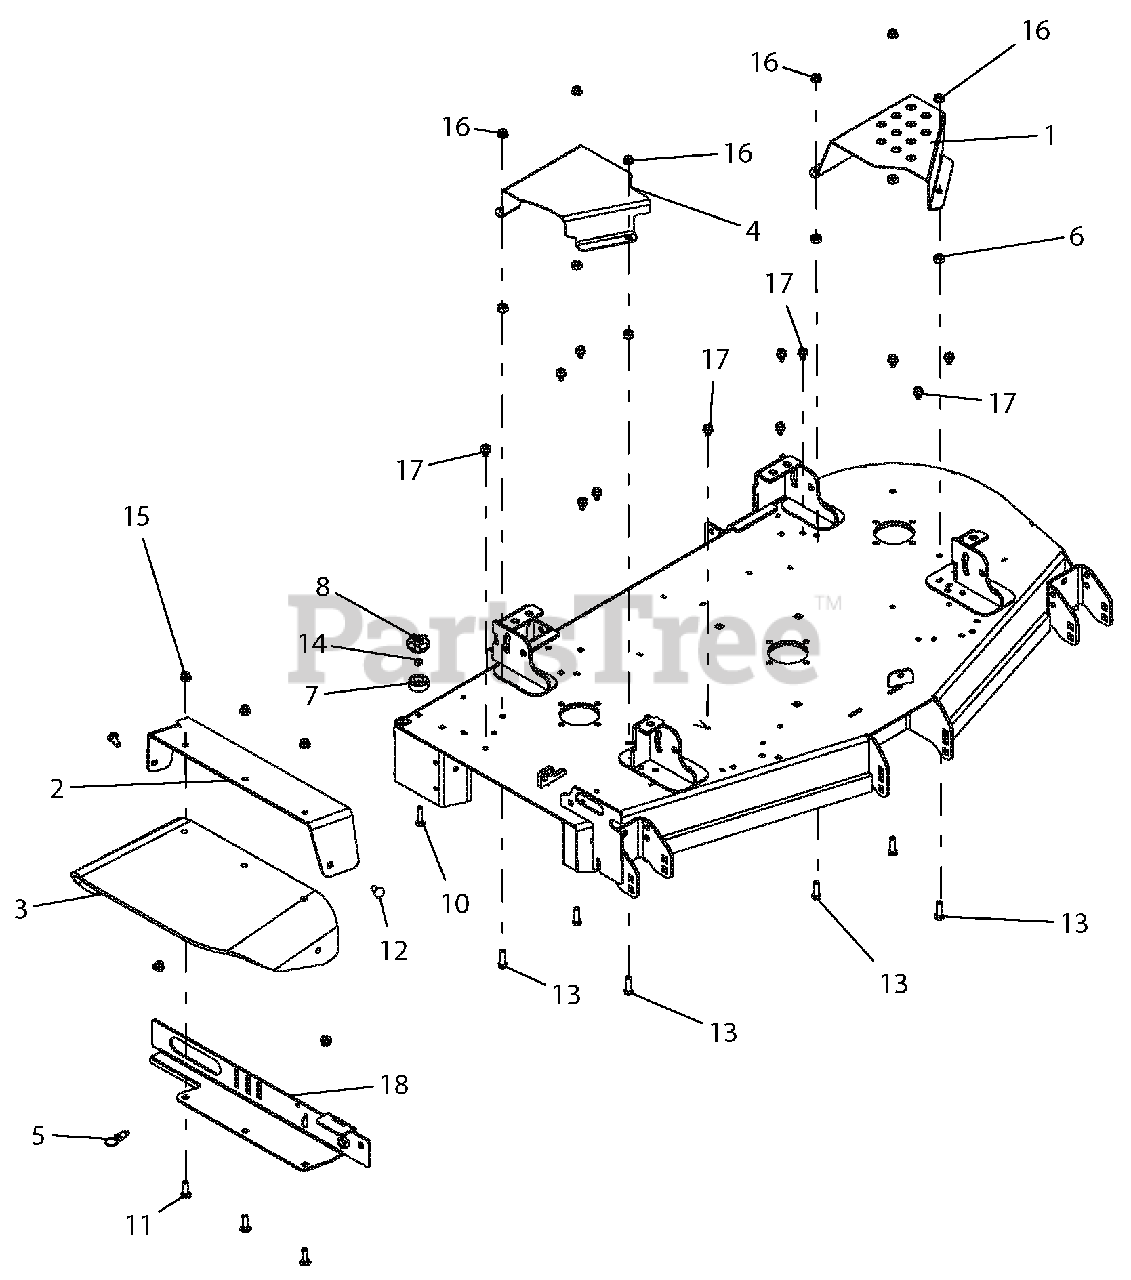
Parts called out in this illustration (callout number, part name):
1	GUARD, 44-52" LH DECK BELT-BLACK
2	DISCHARGE CHUTE SUPPORT W/SAFETY DECAL-RED
3	CHUTE, RUBBER DISCHARGE
4	GUARD, 48"-52" RH DECK BELT-BLACK
5	PULL PIN,.50-13THDX.310 PLNGR
6	NUT-HEAVY HEX .38-16 YWZC
7	BUMPER, RECESSED 1.50 X .63 W/.31 HOLE
8	KNOB, CLAMPING
10	BLT-RDHDSQNK .31-18X1.50 G5 YWZC
11	BLT-RDHDSQNK .38-16X1.25 G5 YWZC
12	BLT-RDHDSQNK .38-16X1.00 G5 YWZC
13	BLT-HEX .38-16X1.25 GR5 YWZC
14	NUT-LK-CTR .31-18 YWZC
15	NUT-LK-NYL-FLG .38-16 YWZC
16	@NUT-SPNLK-FLG .375-16 YWZC
17	SCR-TAP .38-16X.50 HWH TR YWZ
18	WLDMT, 52"-60" DISCH CHUTE MTG-RED
